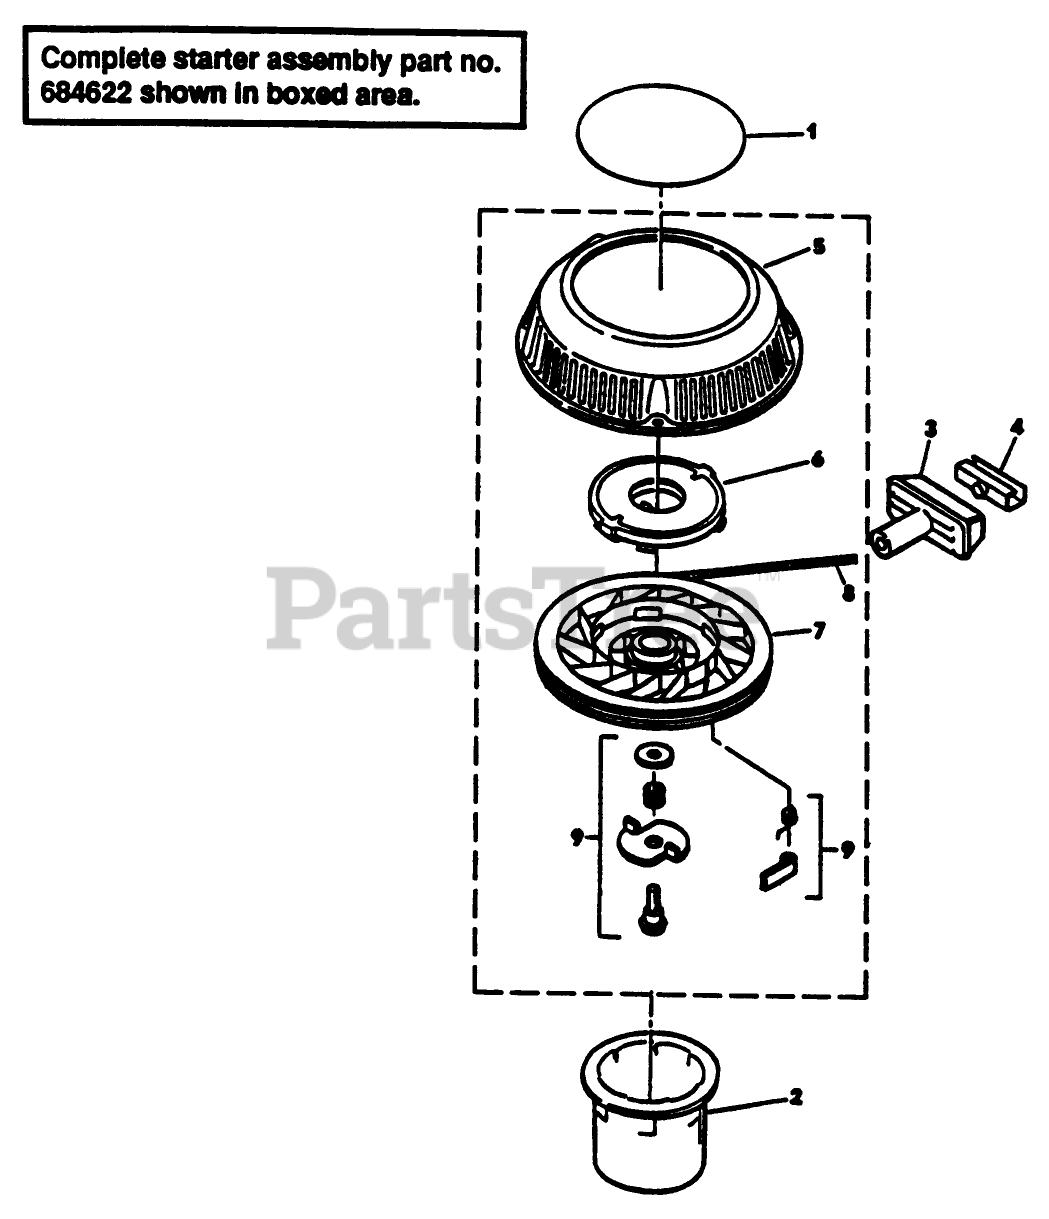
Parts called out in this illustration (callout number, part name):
2	HUB STARTER SM
4	CLIP-STARTER
5	STARTER HOUSING & SHAFT
9	DOG KIT
